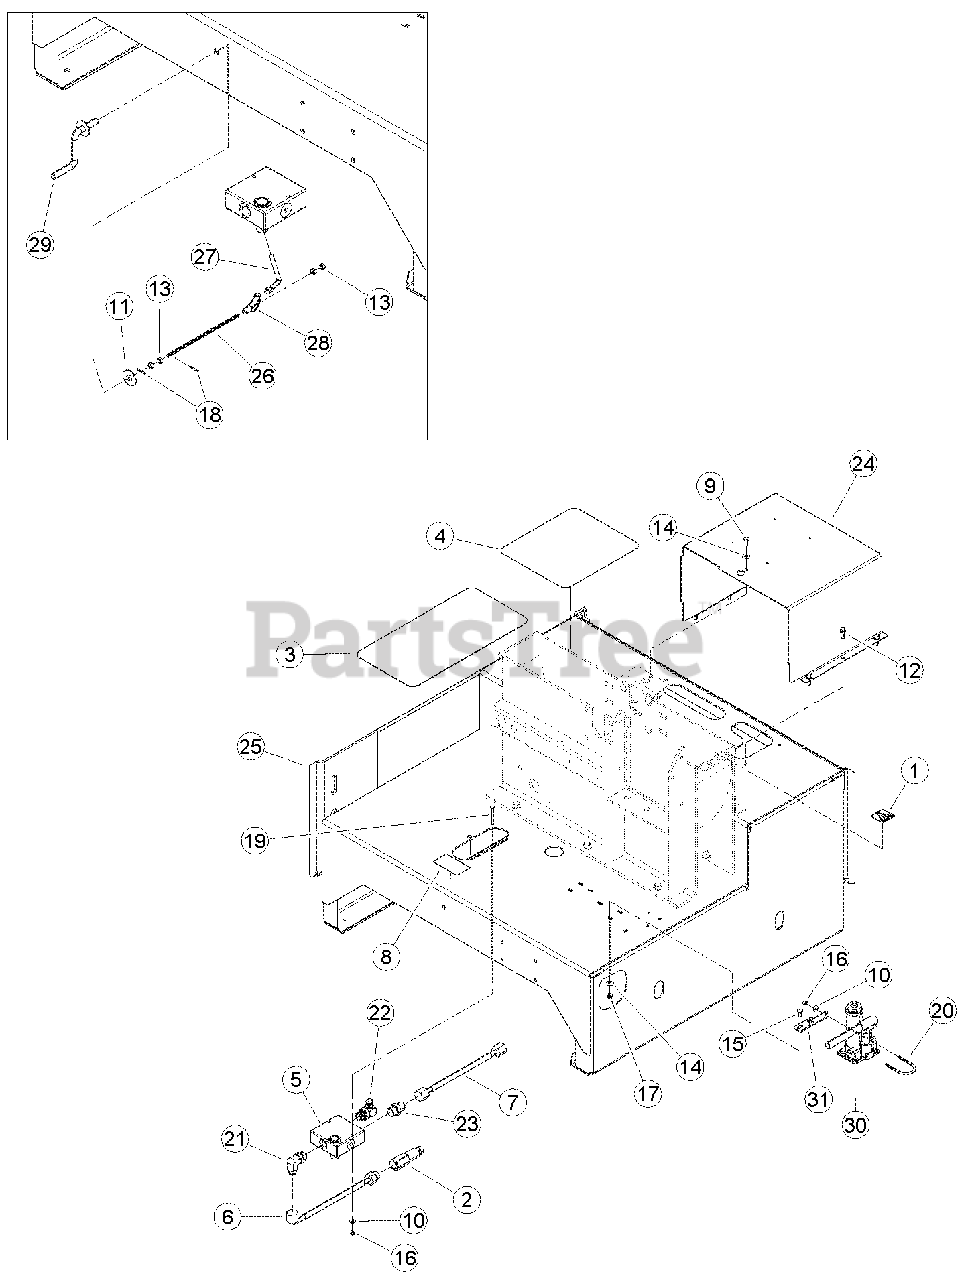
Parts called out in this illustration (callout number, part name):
1	DECAL, SHIELD DANGER ISO
2	COUPLER, MALE QUICKTACH
3	TREAD, SAFETY
4	TREAD, SAFETY
5	VALVE, 30 GPM FLOW CONTROL
6	HOSE, .75 X 119 -12 MORING / -12 FMJIC 90 DEG.
7	HOSE, .75 X 40 -12 FMJIC / -12 FMJIC
8	DECAL, FEED SPEED
9	BOLT, 5/16 X 3/4 HEX HD GR5 ZP (CH800H ONLY)
10	WASHER, 1/4 FLAT ZP
11	WASHER, 1/2 FLAT ZP
12	SCREW, 3/8-16 X 1 LG THD CUTT ZP
13	NUT, 1/4-28 UNF ZP
14	WASHER, 5/16 FLAT ZP
15	BOLT, 5/16 X 7/8 CRG GR5 NC ZP
16	NUT, 1/4 NE NYLOCK ZP
17	NUT, 5/16 NE NYLOCK ZP
18	PIN, 3/32 X 3/4 COTTER
19	BOLT, 1/4 X 2-1/2 HEX HD GR5 ZP
20	U-BOLT, 1/4 X 1-1/2 PIPE
21	ADAPTER, -12 MORING / -12 MJIC 90 DEG.
22	ADAPTER, -12 MORING / -10 MJIC 90 DEG.
23	ADAPTER, -12 MORING / -12 MJIC
24	COVER, HYDRAULIC MOTOR (CH800H)
24	COVER, HYDRAULIC MOTOR (CH500H)
25	WELDMENT, CHIPPER BASE
26	ROD, 1/4-28 THREADED
27	LEVER, FLOW CONTROL
28	CLEVIS, FLOW CONTROL
29	WELDMENT, FEED CRANK
30	JACK, HYDRAULIC 2 TON
31	PLATE, JACK MOUNT
